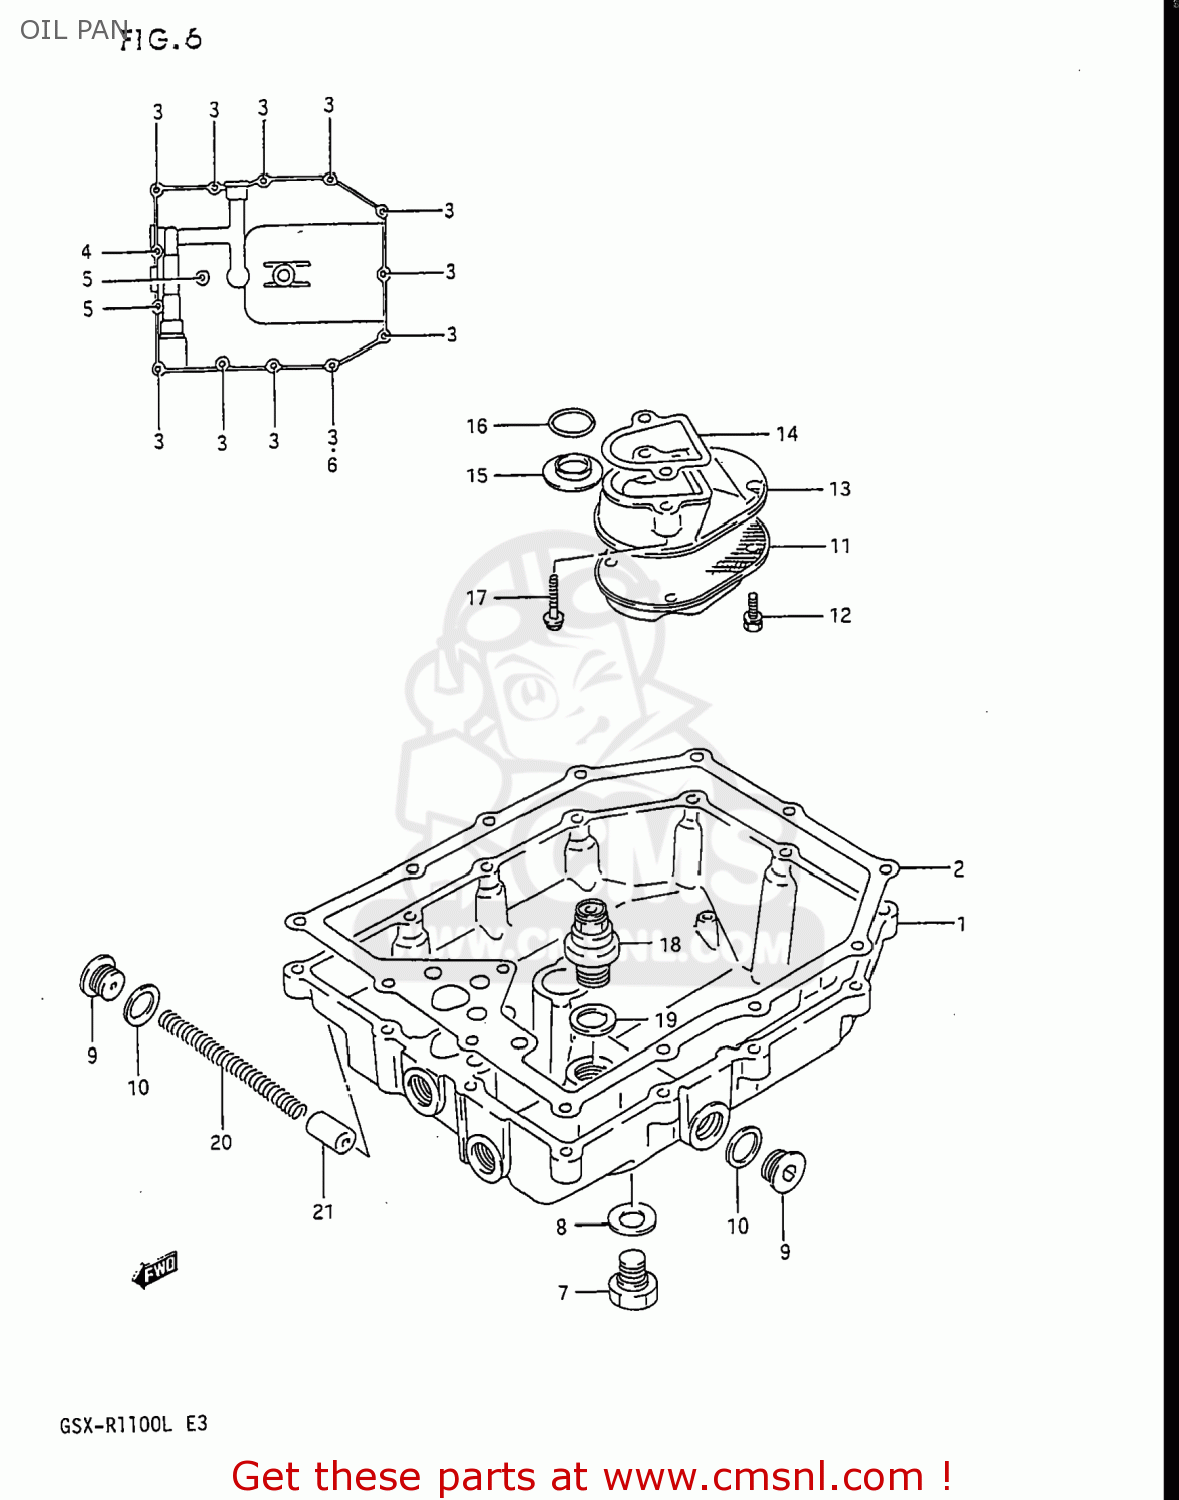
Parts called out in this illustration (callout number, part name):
1	PAN,OIL
2	GASKET,OIL PAN (NAS)
3	BOLT
4	BOLT
5	BOLT
6	GASKET(5.8X11X1.2) (NAS)
7	PLUG
8	GASKET(14X19.2X2) (NAS)
9	PLUG
10	GASKET(16X22X2) (NAS)
11	STRAINER,ENGINE OIL
12	BOLT
13	PROTECTOR,OIL STRAINER
14	GASKET,OIL STRAINER PROTECTOR (NAS)
15	GASKET,OIL OUTLET (NAS)
16	O RING(D:3.2,ID:17.8)
17	BOLT
18	VALVE ASSEMBLY,OIL RELIEF
19	GASKET(16X22X2) (NAS)
20	SPRING
21	PLUNGER,OIL CONTROLL
